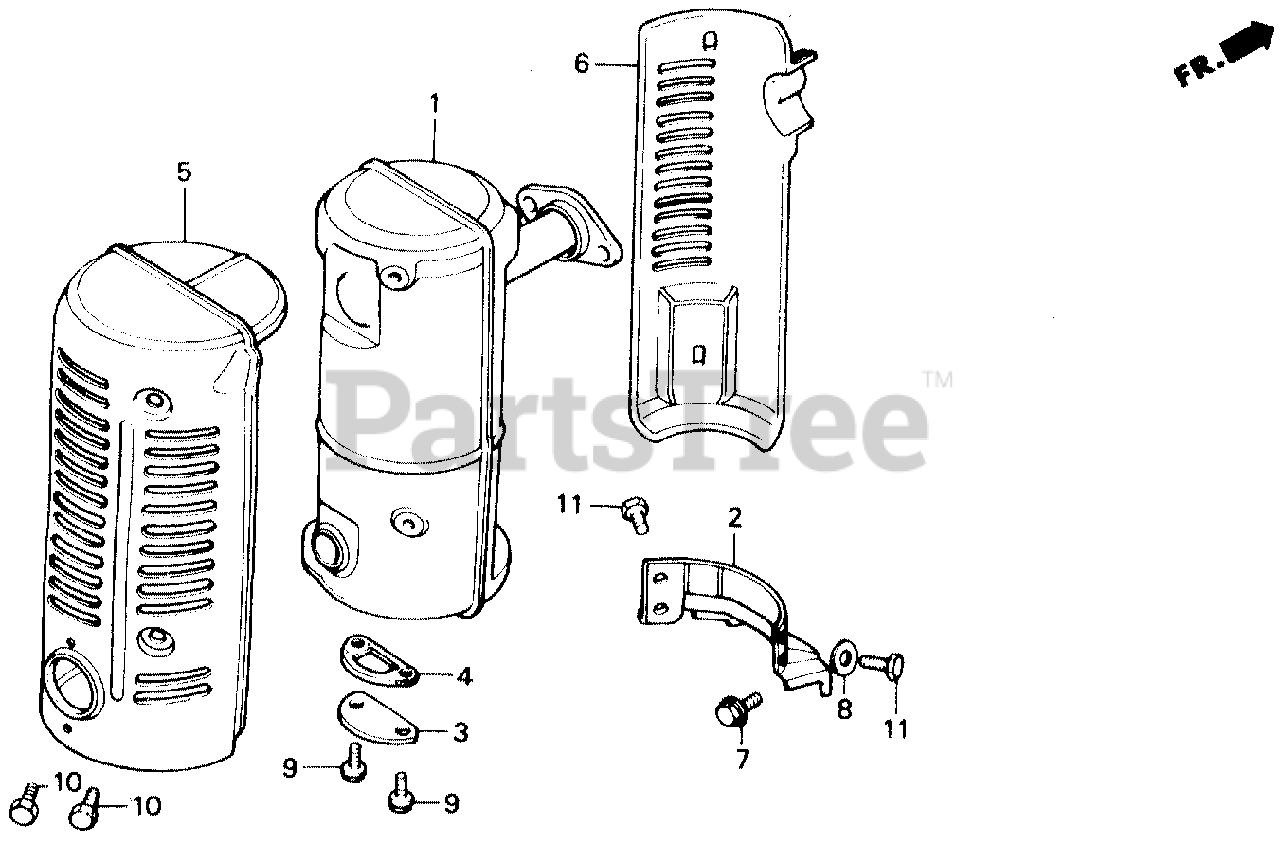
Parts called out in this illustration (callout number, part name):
1	MUFFLER (MUFFLER LID)
2	STAY, MUFFLER
3	LID, MUFFLER
4	GASKET, MUFFLER LID
5	PROTECTOR A, MUFFLER
6	PROTECTOR B, MUFFLER
7	BOLT, FLANGE (8X16)
9	BOLT, HEX. (6X12)
10	BOLT, HEX. (6X6)
11	BOLT, FLANGE (6X10)
